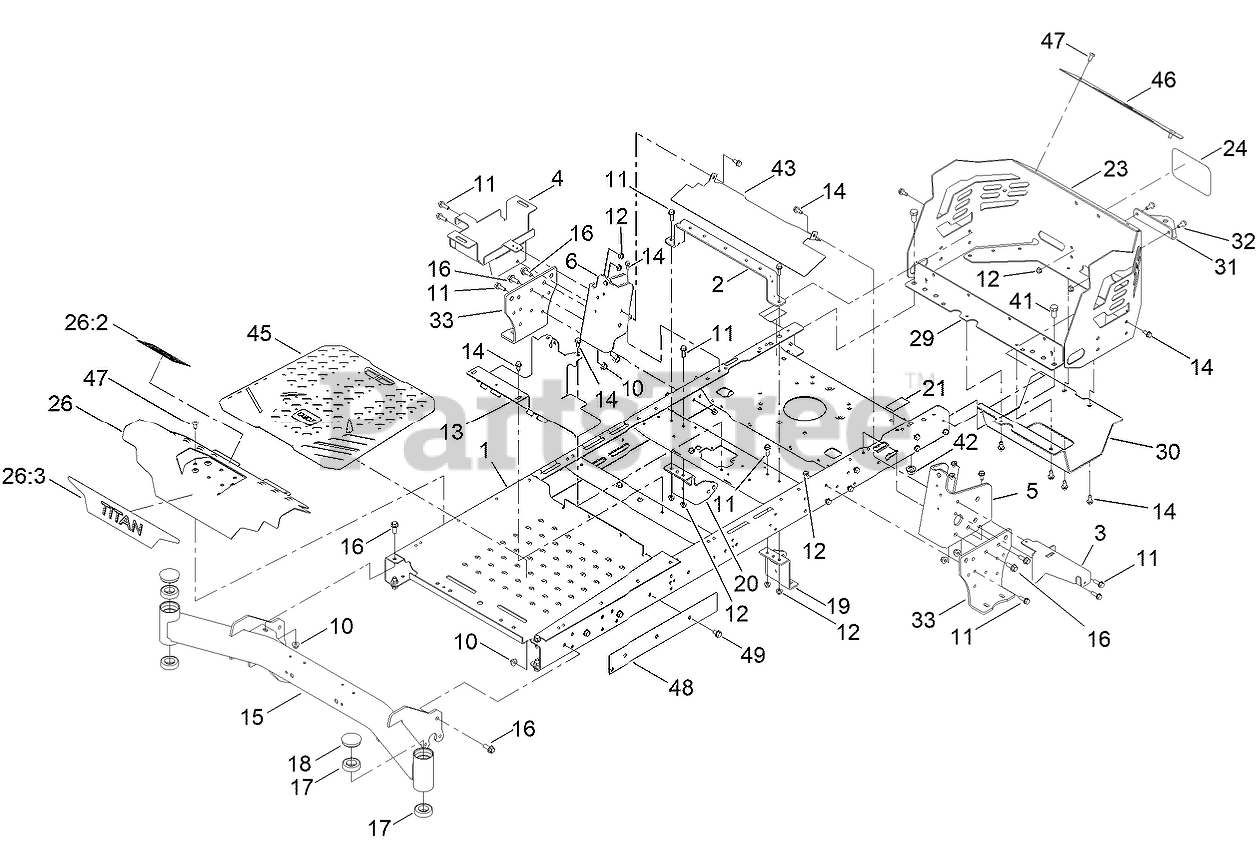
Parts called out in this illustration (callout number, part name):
1	FRAME ASM
2	BRACE-SEAT, REAR (WIDE)
3	BRACKET-SUPPORT, POD (LH)
4	TRAY-BATTERY
5	BRACKET-MOUNTING, LH
6	BRACKET-MOUNTING, RH
10	NUT-HF, NI
11	SCREW-HHF
12	NUT-HF, NI
13	BRACKET-MOUNT
14	SCREW-HWHTF
15	FRONT AXLE ASM
16	SCREW-HHF
17	BEARING-BALL
18	CAP-GREASE
19	MOUNT-HYDRO, FRONT (LEFT)
20	MOUNT-HYDRO, FRONT (RIGHT)
21	DECAL-BYPASS
23	GUARD-ENGINE
24	DECAL
26	FOOTREST-TITAN
26:2	DECAL-DANGER
26:3	DECAL-TITAN
29	CROSSMEMBER-REAR, WIDE
30	GUARD-MUFFLER
31	BRACKET-HITCH
32	SCREW-HHF
33	MOUNT-HYDRO
41	SCREW-HH
42	NUT-LOCK
45	FLOOR MAT
46	TRIM-GUARD, ENGINE
48	PLATE-FRAME
49	SCREW-HWHTF
